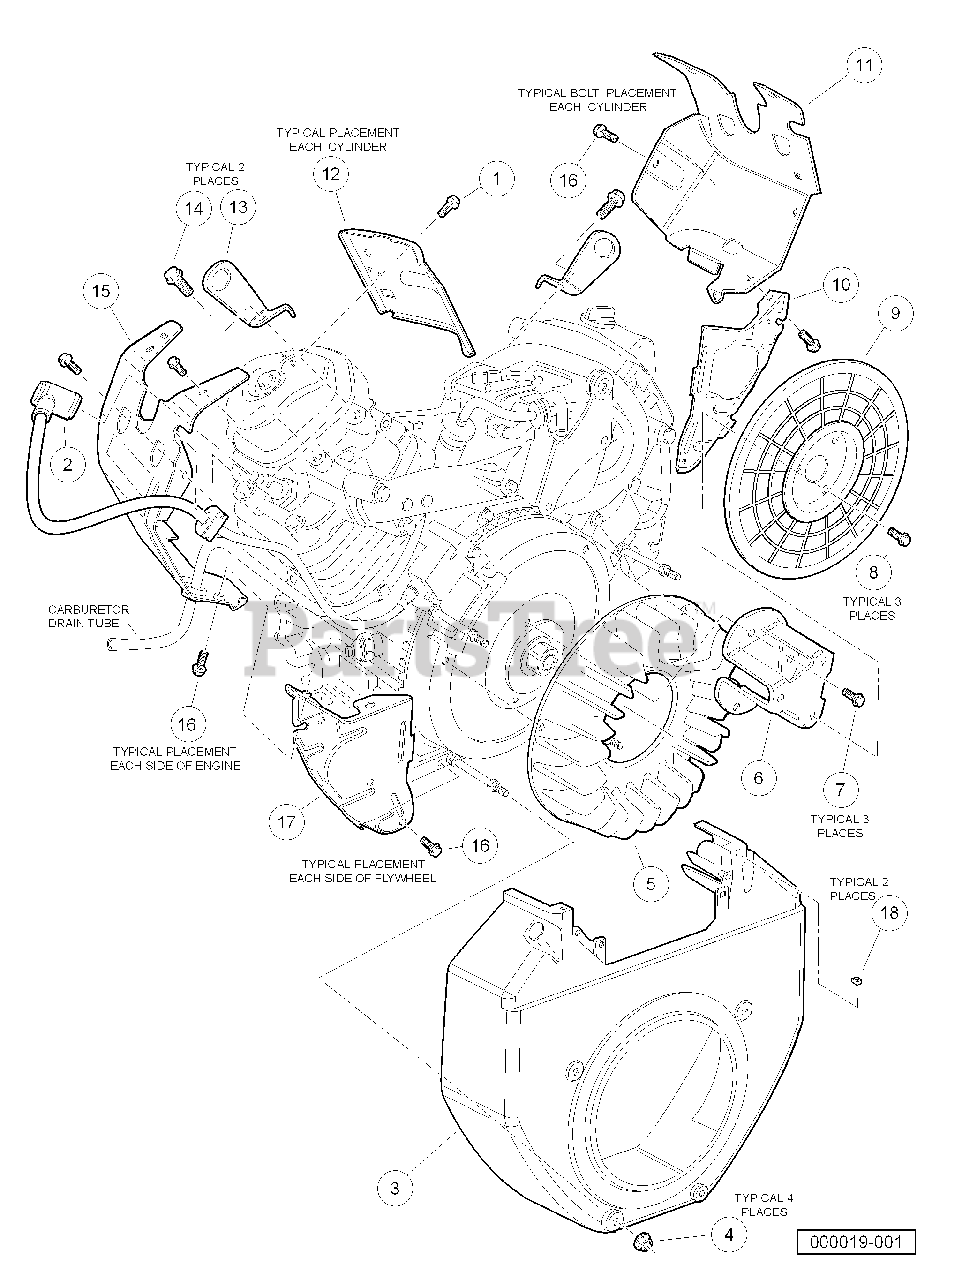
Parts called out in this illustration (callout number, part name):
1	Bolt, Flange Head, M6 X 11 X 4
2	Cap Assy, Noise Suppressor
3	Cover, Fan, Bright Red
4	Nut, Flange, M6
5	Fan, Cooling
6	Holder, Screen Grid
7	Bolt, Flange Head, M8 X 1.25 X 16
8	Bolt, Flange Head, M6 X 1 X 12
9	Grid Screen, PTO
10	Plate, R Side
12	Shroud, Head
13	Hanger, Engine
14	Bolt, Flange Head, M8 X 1.25 X 20
16	Bolt, Flange Head, M6 X 1 X 12
17	Plate, Left Side
18	Nut, Square, 5mm
